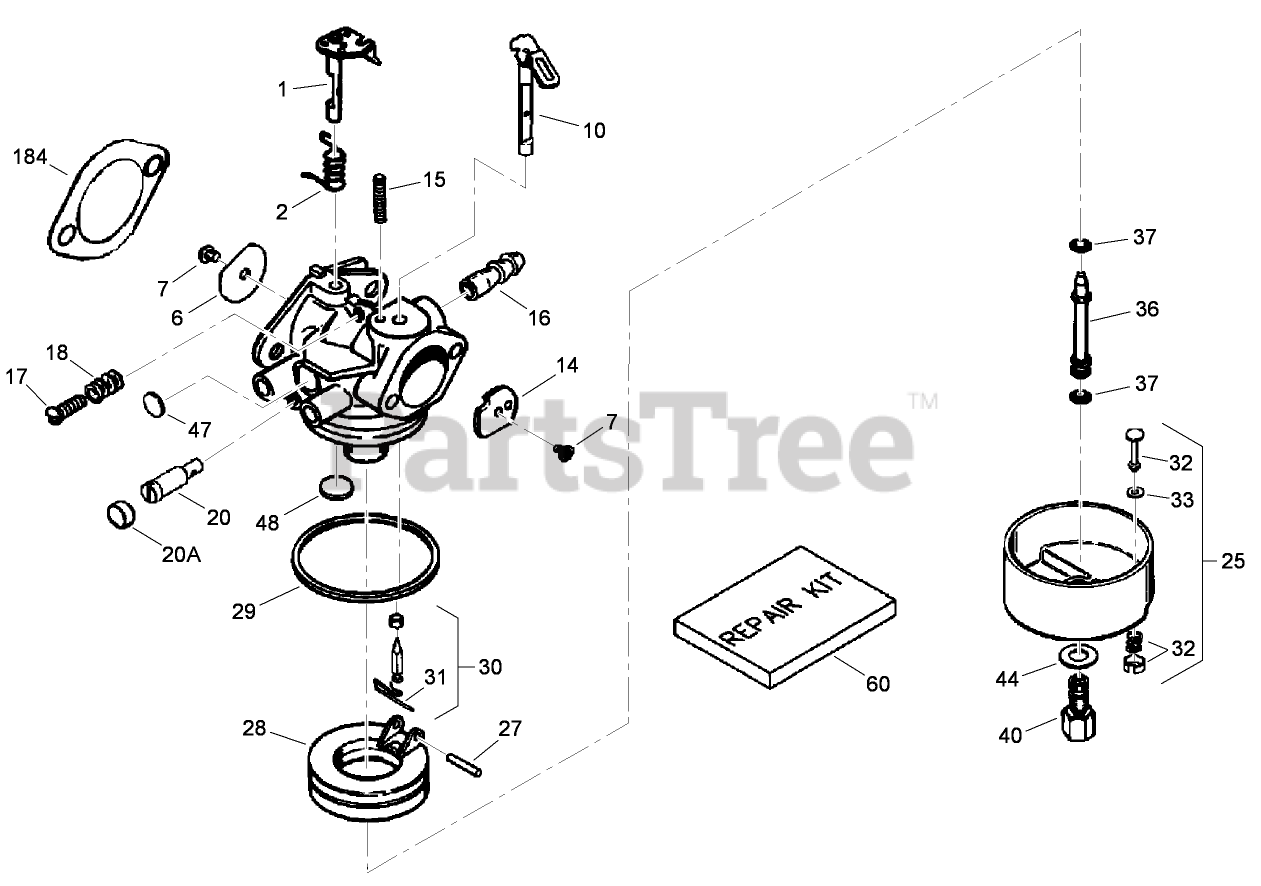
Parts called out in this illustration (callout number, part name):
1	Throttle Shaft and Lever ASM
2	Spring-Return, Throttle
6	Shutter-Throttle
7	Screw-Shutter
10	Choke Shaft and Lever ASM
14	Shutter-Choke
15	Spring-Positioning, Choke
16	Fitting-Fuel
17	Screw-Throttle Crack Screw / Idle Speed
18	Spring-Tension
20	Screw-Restrictor, Idle
20A	Cap-Screw, Idle Restrictor
25	Float Bowl Asm. (Incl. Ref. # 32, 33)
27	Shaft-Float
28	Float
29	O Ring-Bowl, Float
30	Inlet Needle, Seat Clip Assy. (Incl. No. 13)
31	Clip-Spring
32	Bowl Drain ASM
33	Gasket-Plunger, Drain
36	Tube-Nozzle, Main
37	O-Ring
40	Nut-Bowl, High Speed
44	Washer-Nut, Bowl
47	Plug-Welch, Idle Mixture Well
48	Plug-Welch, Atmospheric Vent
60	Repair Kit
184	Gasket-Carburetor To Intake Pipe
